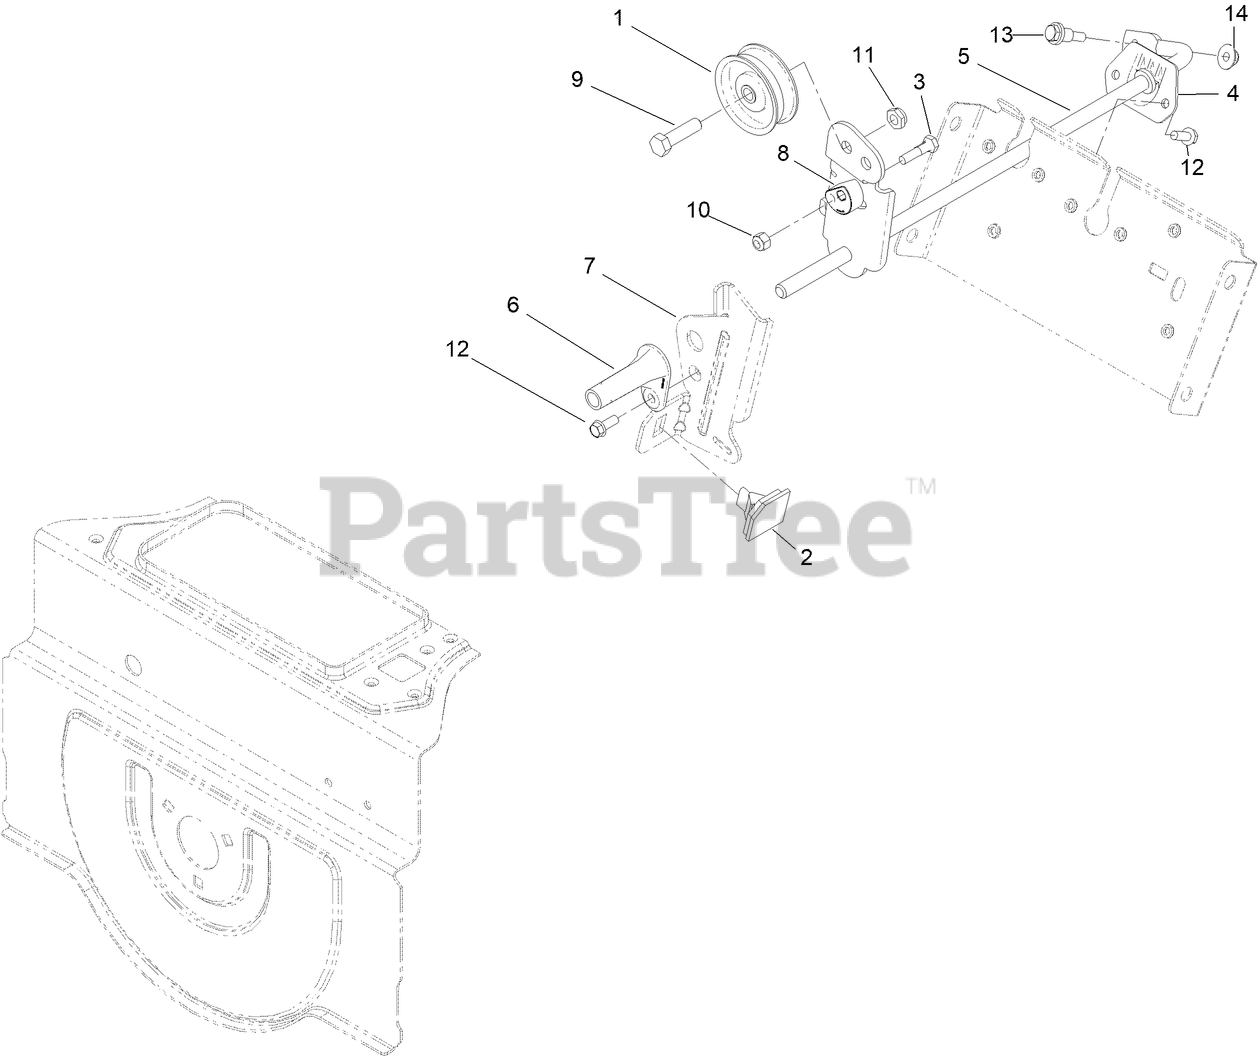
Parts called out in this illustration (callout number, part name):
1	PULLEY-IDLER
2	PAD-BRAKE
3	BOLT-PIVOT, ECCENTRIC
4	BUSHING-ROD, CLUTCH
5	IMPELLER CLUTCH ASM
6	PIVOT-BRAKE, IMPELLER
7	ARM-BRAKE, IMPELLER
8	ECCENTRIC-BRAKE, IMPELLER
9	SCREW-HH
10	NUT-LOCK, NI
12	SCREW-HWH
13	BOLT-SHOULDER
14	NUT-HF
